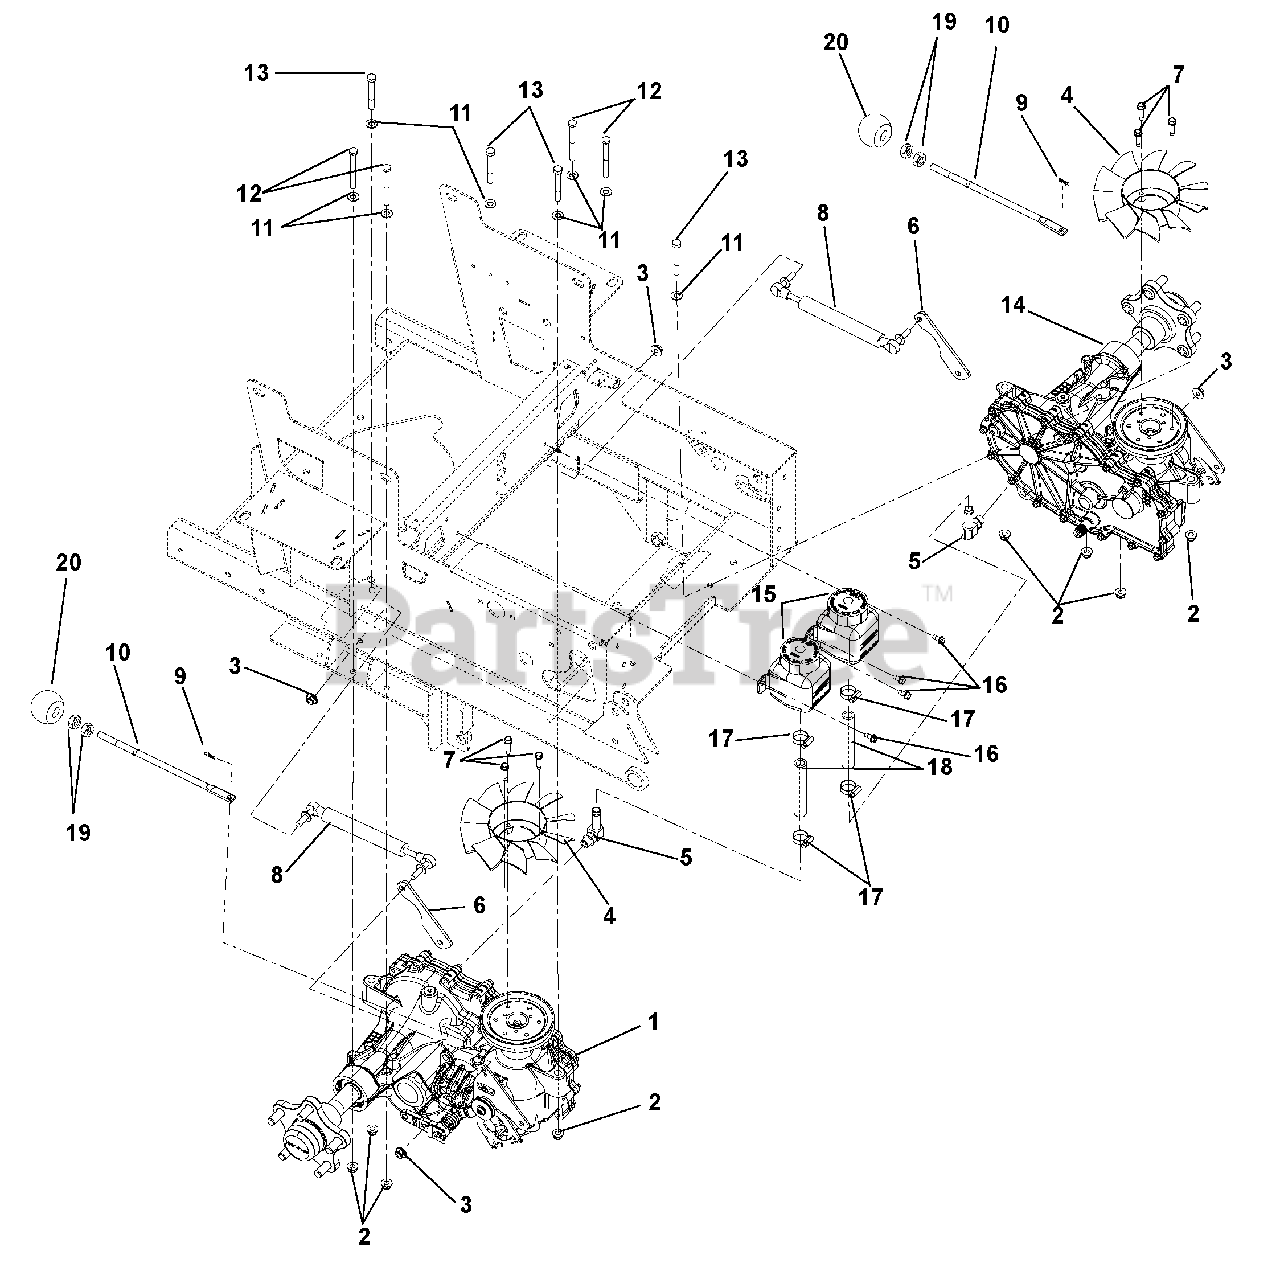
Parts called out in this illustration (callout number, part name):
1	Transaxle, Right Hand (Serial No. 002000 & up)
2	Nut, .31-18 Nyloc Flange
3	Nut, M8-1.25 Whiz Lock
4	Fan, 2800 Series Cooling
5	Fitting, Hydraulic (90 DEG)
6	Plate, Control Reforcement
7	Screw, Tapping .25-20 x 1.00 Hex Washer Head Thread Rolling
9	Pin, Hair-Internal .06 x .18 x .77
10	Lever, 100I Dump Valve
11	Washer, Flat-Steel .344 x .688 x .065
12	Bolt, Hex .31-18 x 3.00 Grade 5
13	Bolt, Hex .31-18 x 2.50 Grade 5
14	Transaxle, Left Hand (Serial No. 002000 & up)
15	Tank, Expansion ZT2800 (Serial No. 001000 & up)
16	Screw, Tapping .25-20 x .50 Hex Washer Head Thread Rolling
17	Clamp, .88 Diameter Hose
18	Hose, 100I Hydro Overflow
19	Nut, Jam .312-18
20	Knob, Black Ball .312-18 x 1.00
